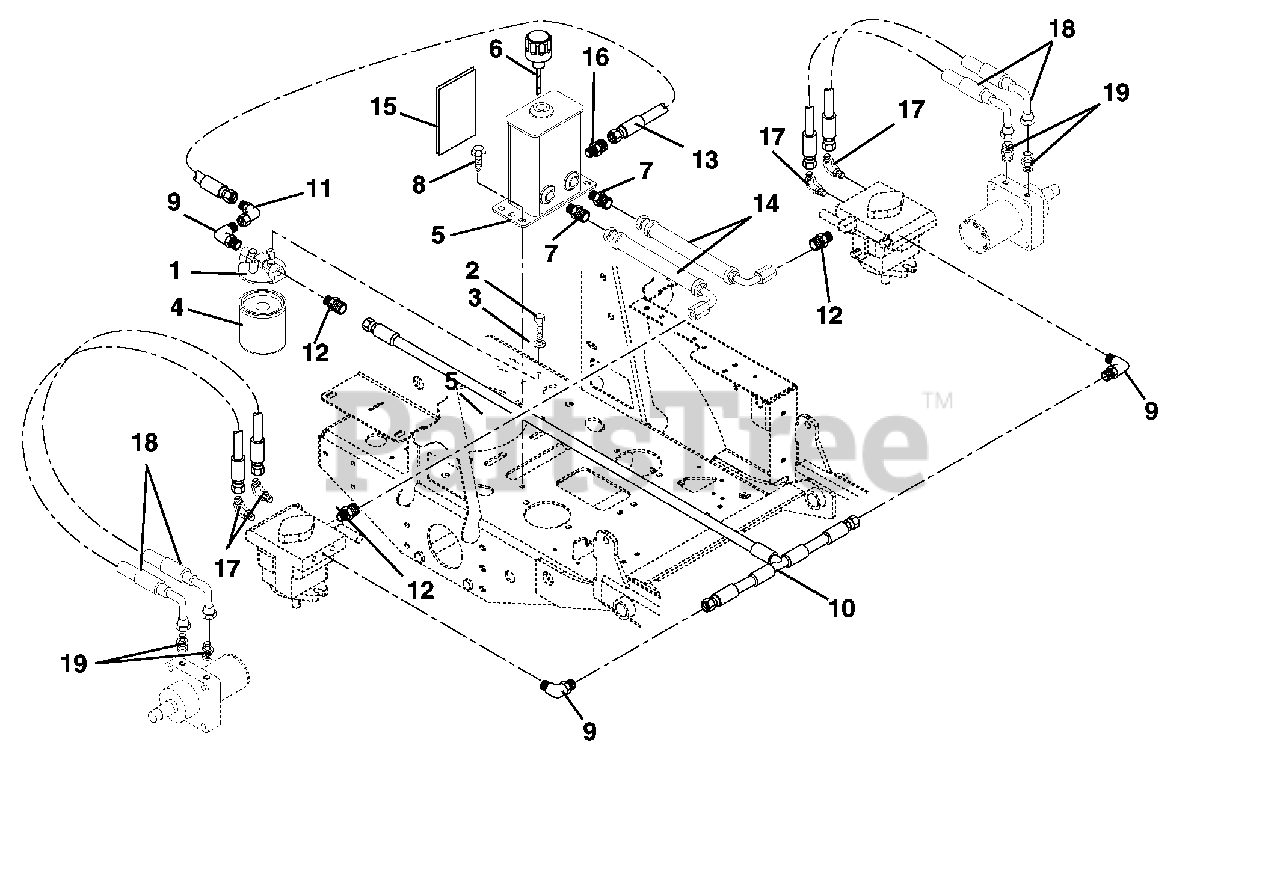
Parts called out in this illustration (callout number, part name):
1	Head, Filter
2	Bolt, Hex .25-20 x .50 Grade 5
3	Washer, Locking .25 x .062
4	Oil Filter
5	Tank, Hydraulic
6	Hydraulic Tank Dipstick
7	Adapter, Straight
8	Screw, Tapping .38-16 x .50 Hex Washer Head
9	Adapter
10	Hose, Hydraulic
11	Adapter
12	Adapter, Pipe .56-18 "O"RING To .56-18
13	Hose,Hydraulic Valve To Tank
14	Hose, Hydraulic
15	Shield, Heat 5.50 x 4.50
16	Fitting, Hydraulic 45 Degree
17	Fitting, Hydraulic
18	Hose, Hydraulic
19	Adapter, Hydraulic
